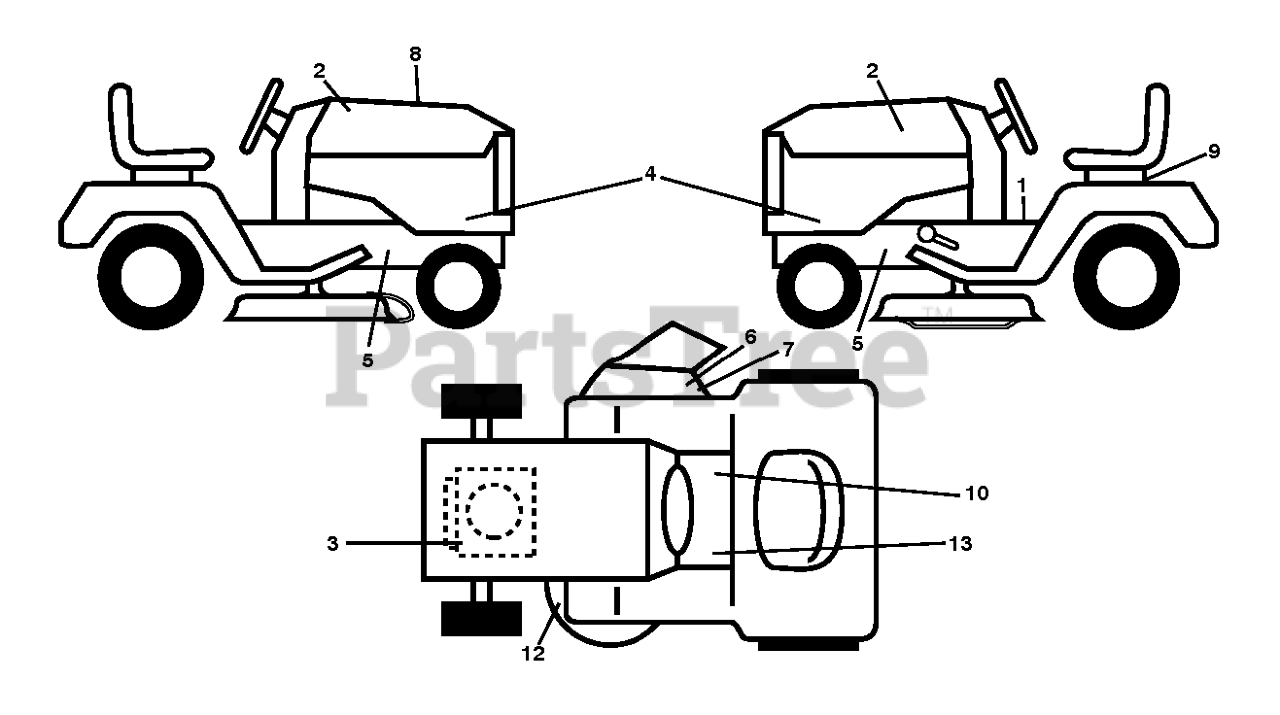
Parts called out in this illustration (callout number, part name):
1	DECAL.READ.OWN.MAN.SYMBOL.LT
2	DECAL.BADGE.170MM.TEXTLOGO.
3	DECAL.ENGINE.WARNING
4	DECAL DECAL.SDPNL.HUSQLT.LTH20
5	DECAL.CHASSIS.HOT.MUFFLER
7	DECAL.DFLCTR.WARNNG.CTFNGR.SYM
8	DECAL DECAL.RPL.BSM33.ENDU.TLW
9	DECAL BTRY SYMBOLS
10	DECAL.PARKING.BRAKE.SADDLE.LT
11	DECAL.CUTFINGER.CE.02
12	DECAL.DECK.SCH.36,38,94.NONCR
13	DECAL.FNDR.SDLE.BRAKE.CLUTCH.6
